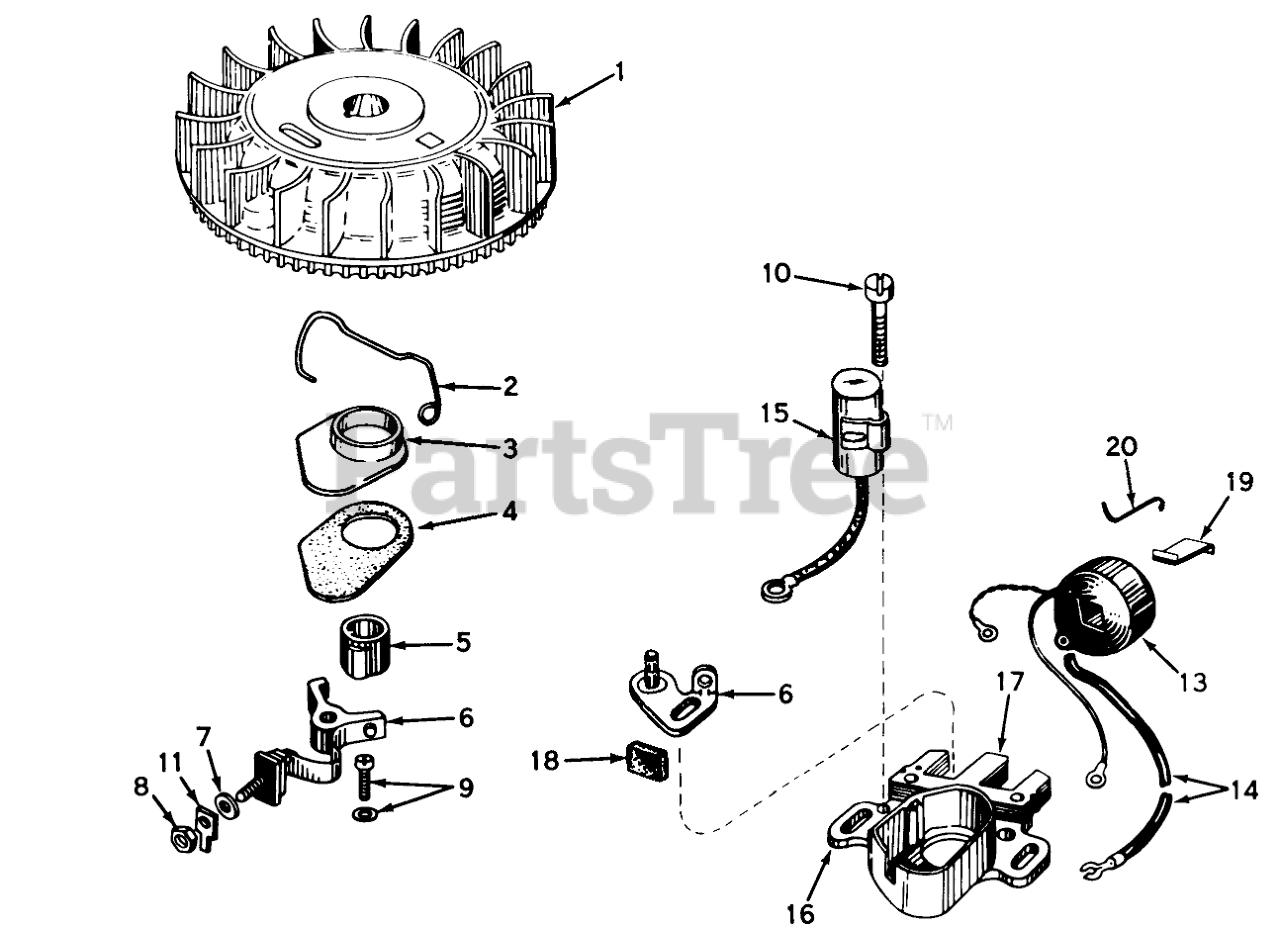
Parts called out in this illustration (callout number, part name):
1	FIywheel
2	Spring Breaker Box
3	Cover, Dust
4	Gasket Dust Cover
5	Cam, Breaker
6	Breaker Assy.
9	Breaker Screw
10	Condenser Screw
11	Terminal
13	Coil Assy. (Incl. Ref. 14, 15 & 19)
14	Wire, Lead
15	Condenser
16	Core & Plate
17	Stator Assy. (Incl. Ref. 2, 3, 5 thru 14 & 16 thru 19)
18	Felt,Cam Wiper
19	Spring Coil Wedge
20	Clip, Coil
